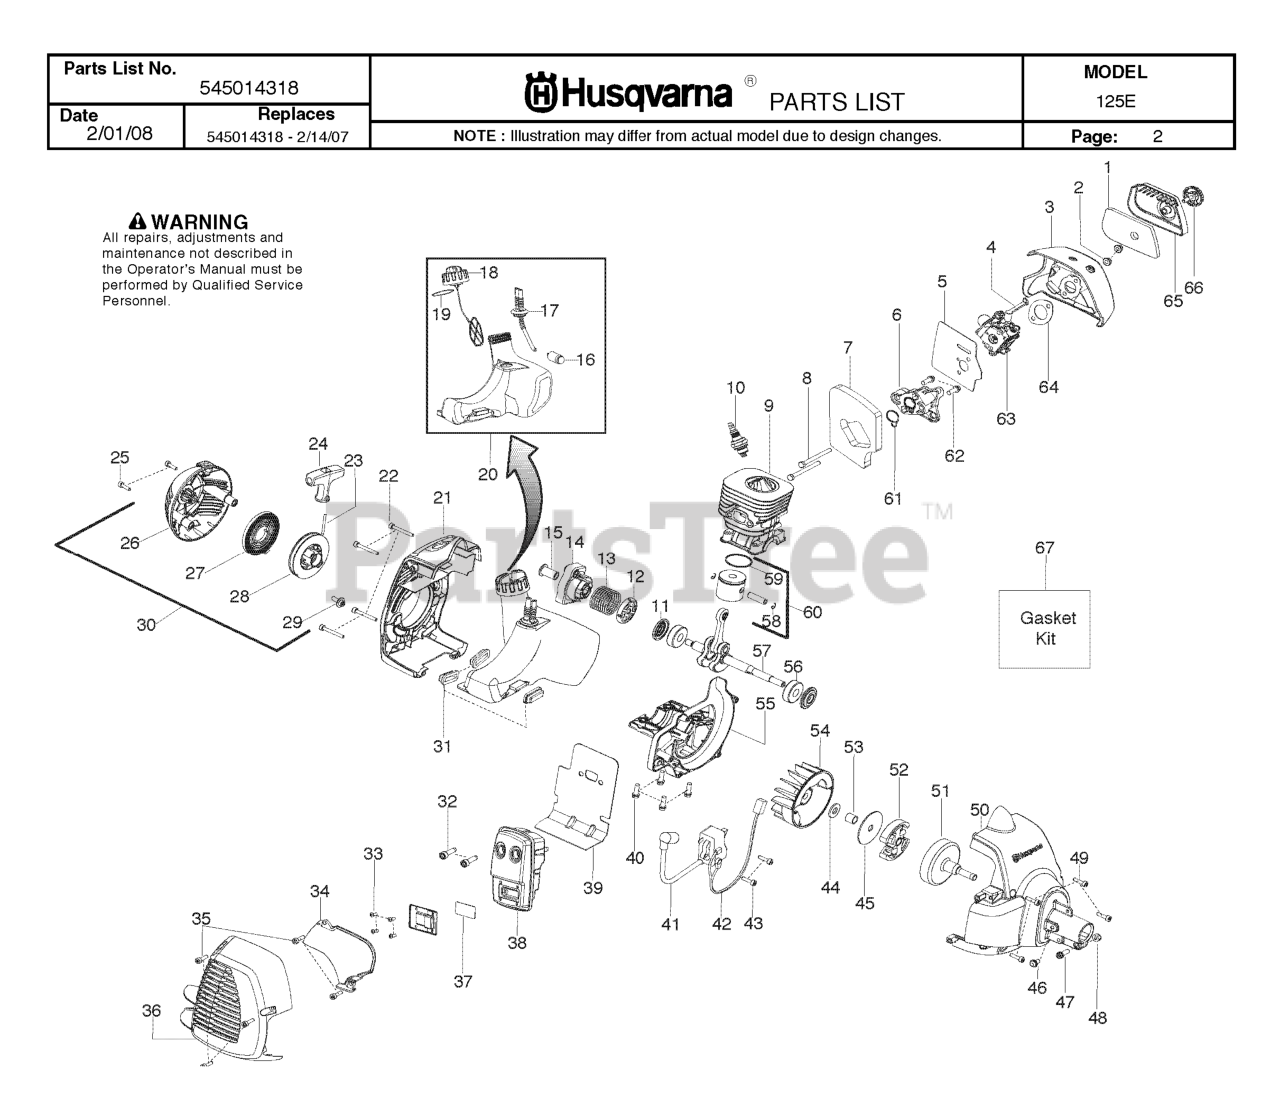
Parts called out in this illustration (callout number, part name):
1	FILTER AIRBOX
3	RP_AIR BOX
4	CHOKE LEVER
5	KIT GASKET CARB
6	CARB ADAPTOR
7	KIT GASKET 28CC TRIMMER
8	BOLT CARB ADAPTOR
9	CYLINDER
10	Plug - Spark (RCJ-8Y)
11	KIT SEAL CRANKSHAFT
12	WASHER STARTER
13	SPRING STARTER CUP
14	ASSY-STARTER CUP
15	COUPLING STARTER
16	FUEL PICK-UP ASSY
17	KIT FUEL LINE
18	ASSY-CAP W/RETAINER
19	O RING NITRILE
20	FUEL TANK ASSY
21	REAR SHROUD
24	STARTER HANDLE GRAY
25	SCREW M5-0.8X30MM
26	STARTER HOUSING
27	%KIT STARTER SPRING
28	KIT STARTER PULLEY
30	ASSY-STARTER HSG.
31	ISOLATOR FUEL TANK
32	BOLT MUFFLER
33	SCREW-10-16 X 1/2 HI-LO
34	SHIELD HEAT
35	SCREW M4 X 1.75 PT 16MM
36	GUARD-MUFFLER
37	KIT SPARK ARRESTOR SCREEN
38	ASSY-MUFFLER
39	GASKET PAPER METAL
40	SCREW-M5-0.8 X 25MM(TAP)
41	IGNITION MODULE MBU-7
42	ASSY MODULE LEAD WIRE
43	SCREW M4 X .70 TT 16MM
44	WASHER CLUTCH
45	WASHER-CLUTCH
48	LOCKNUT-HEX 10-24
49	SCREW M4 X .70 TT 16MM
50	FAN HSG ASSY
51	ASSY-CLUTCH DRUM
52	%KIT CLUTCH ASSY
53	SPACER FLYWHEEL
55	CRANKCASE CASTING
56	BEARING RADIAL BALL (6201)
57	KIT CRANKSHAFT ASSY
58	WRIST PIN RET.
59	RING PISTON
60	KIT PISTON 28CC TRIMMER
61	KIT GASKET 28CC TRIMMER
62	SCREW-M5-0.8 X 25MM(TAP)
63	CARBURETOR KIT W38
64	KIT GASKET 28CC TRIMMER
65	COVER-AIR BOX
66	KNOB ASSY AIRBOX COVER
67	KIT GASKET 28CC TRIMMER
